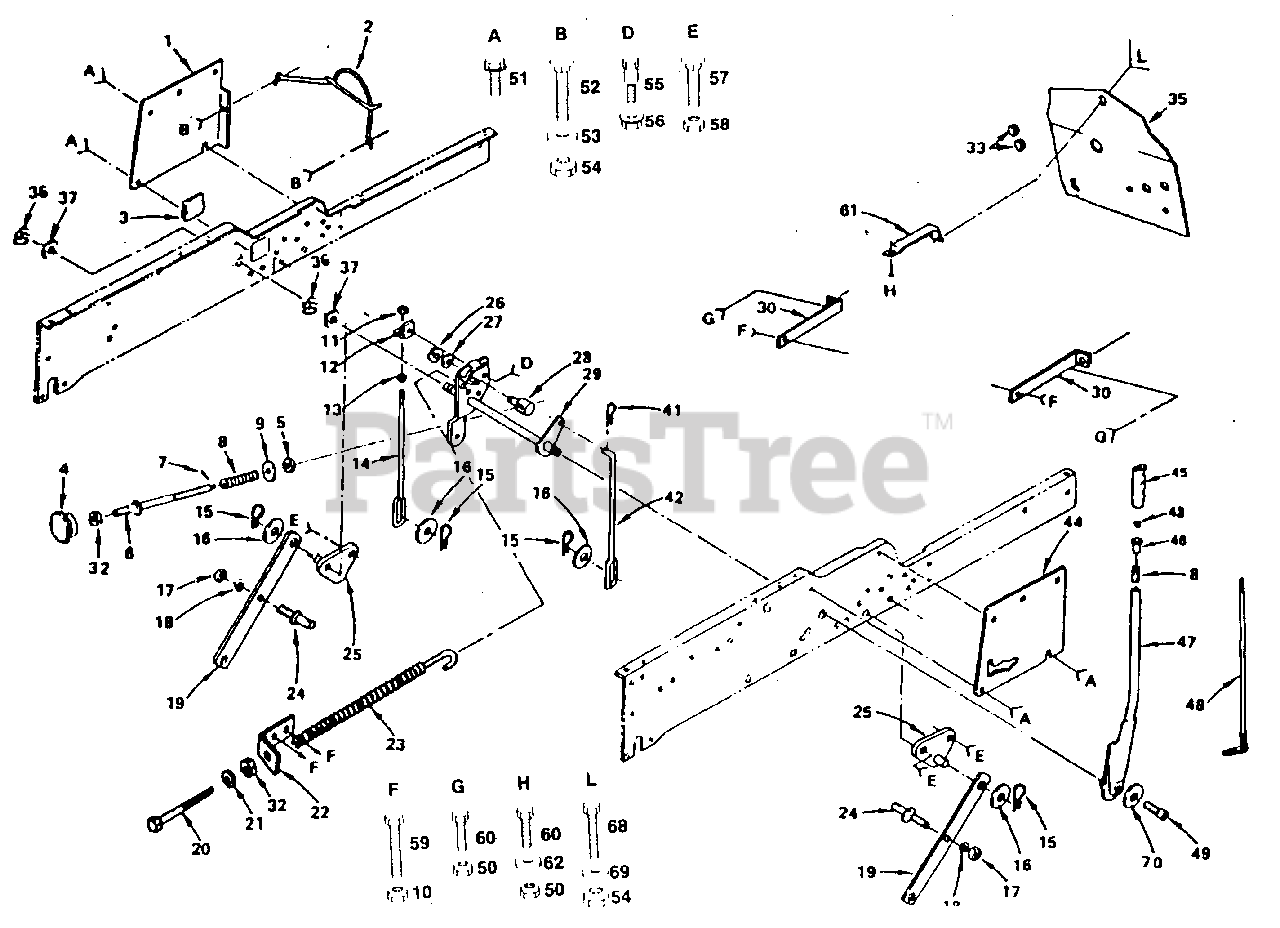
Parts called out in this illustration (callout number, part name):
1	Panel, Side, L.H.
2	Guard Assembly, Belt, Engine (AYP part number)
3	Cover, Access (AYP part number)
4	Handle, Adjust, Lift (AYP part number)
5	Nut (AYP part number)
6	Rod, Adjust, Lift (AYP part number)
7	Pin, Cotter (AYP part number)
8	Spring (AYP part number)
9	Washer 13/32 x 5/8 x 16 Ga. (AYP part number)
10	Locknut 3/8-16
11	Locknut, Hex w/Washer 3/8-16 (AYP part number)
12	Bracket, Lift, L.H. (AYP part number)
13	Nut, Hex 3/8-16 (AYP part number)
14	Link, Lift, L.H. (AYP part number)
15	Retainer, Spring (AYP part number)
16	Washer 17/32 x 1 x 16 Ga. (AYP part number)
17	Nut, Hex 1/2-13 (AYP part number)
18	Washer, Lock 1/2 (AYP part number)
19	Arm, Suspension (AYP part number)
20	Bolt, Adjust, Spring, Assist (AYP part number)
21	Washer 13/32 x 13/16 x 16 Ga. (AYP part number)
22	Bracket, Spring, Assist (AYP part number)
23	Spring Assembly, Assist, Lift (AYP part number)
24	Stud, Pivot Center (AYP part number)
25	Bracket, Suspension (AYP part number)
26	Klip Ring (AYP part number)
27	Washer 15/32 x 3/4 x 16 Ga. (AYP part number)
28	Trunnion, Stop Depth
29	Shaft, Lift (AYP part number)
30	Bracket, Shield, Heat Side (AYP part number)
32	Nut, Hex Jam 3/8-16 (AYP part number)
33	Grommet (AYP part number)
35	Base, Shield, Heat
36	Klip Ring (AYP part number)
37	Washer 29/32 x 1-1/4 x 16 Ga. (AYP part number)
41	Retainer, Spring (AYP part number)
42	Link, Lift, R.H. (AYP part number)
43	Button, Plunger (AYP part number)
44	Panel, Side, R.H.
45	Grip, Handle (AYP part number)
46	Plunger, Lever, Lift (AYP part number)
47	Lever Assembly, Lift (AYP part number)
48	Rod Assembly, Lever (AYP part number)
49	Bolt, Hex 3/8-16 x 1-1/2 (AYP part number)
50	Locknut 1/4-20 (AYP part number)
51	Screw, Hex Washer Thd. 3/8-16 x 1/2 (AYP part number)
52	Bolt, Carrlage 5/16-18 x 1 (AYP part number)
53	Washer 11/32 x 1 x 10 Ga. (AYP part number)
54	Locknut 5/16-18
55	Bolt, Shoulder (AYP part number)
56	Nut, Hex Flange 1/4-20
57	Bolt, Carrlage 3/8-16 x 3/4 (AYP part number)
58	Nut, Centerlock 3/8-16 (AYP part number)
59	Bolt, Hex 3/8-16 x 1 (AYP part number)
60	Bolt, Hex 1/4-20 x 1/2 (AYP part number)
61	Brace, Heat Shield
62	Washer 9/32 x 1/2 x 16 Ga. (AYP part number)
68	Bolt, Hex 5/16-18 x 3/4 (AYP part number)
69	Washer 11/32 x 3/4 x 16 Ga. (AYP part number)
70	Washer, Lock 3/8
